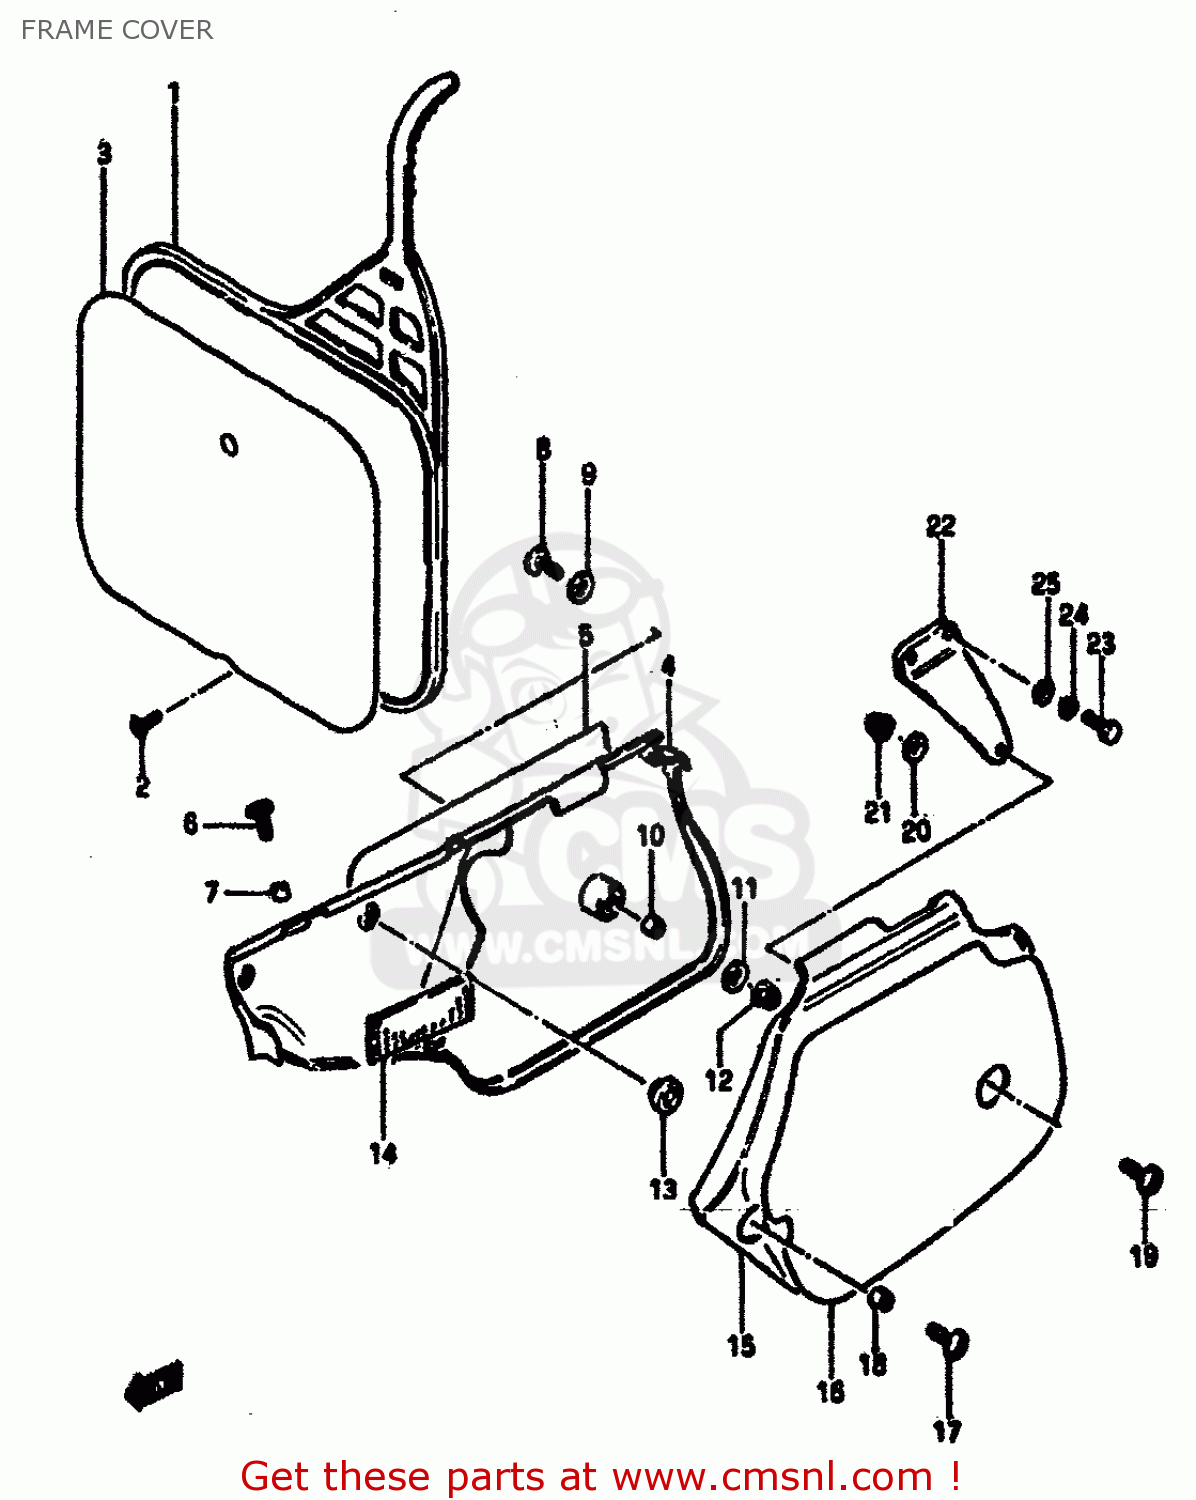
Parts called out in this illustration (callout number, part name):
1	PLATE,NUMBER,FRONT
2	SCREW
3	TAPE,FRONT NUMBER PLATE
4	COVER,FRAME,RIGHT
5	EMBLEM,NUMBER PLATE,RIGHT
6	SCREW(6X14)
7	SPACER (6.1X8X3.5)
8	SCREW(6X20)
9	WASHER FRAME COVER
10	SPACER
11	GASKET
12	NUT
13	CUSHION
14	HEAT SHIELD,FRAME COVER
15	COVER,FRAME,LEFT
16	EMBLEM,NUMBER PLATE,LEFT
17	SCREW(6X14)
18	SPACER (6.1X8X3.5)
19	SCREW(6X20)
20	WASHER FRAME COVER
21	NUT
22	STAY,FRAME COVER,LEFT
23	BOLT
24	WASHER,LOCK
25	WASHER(6.5X16X1.2)
